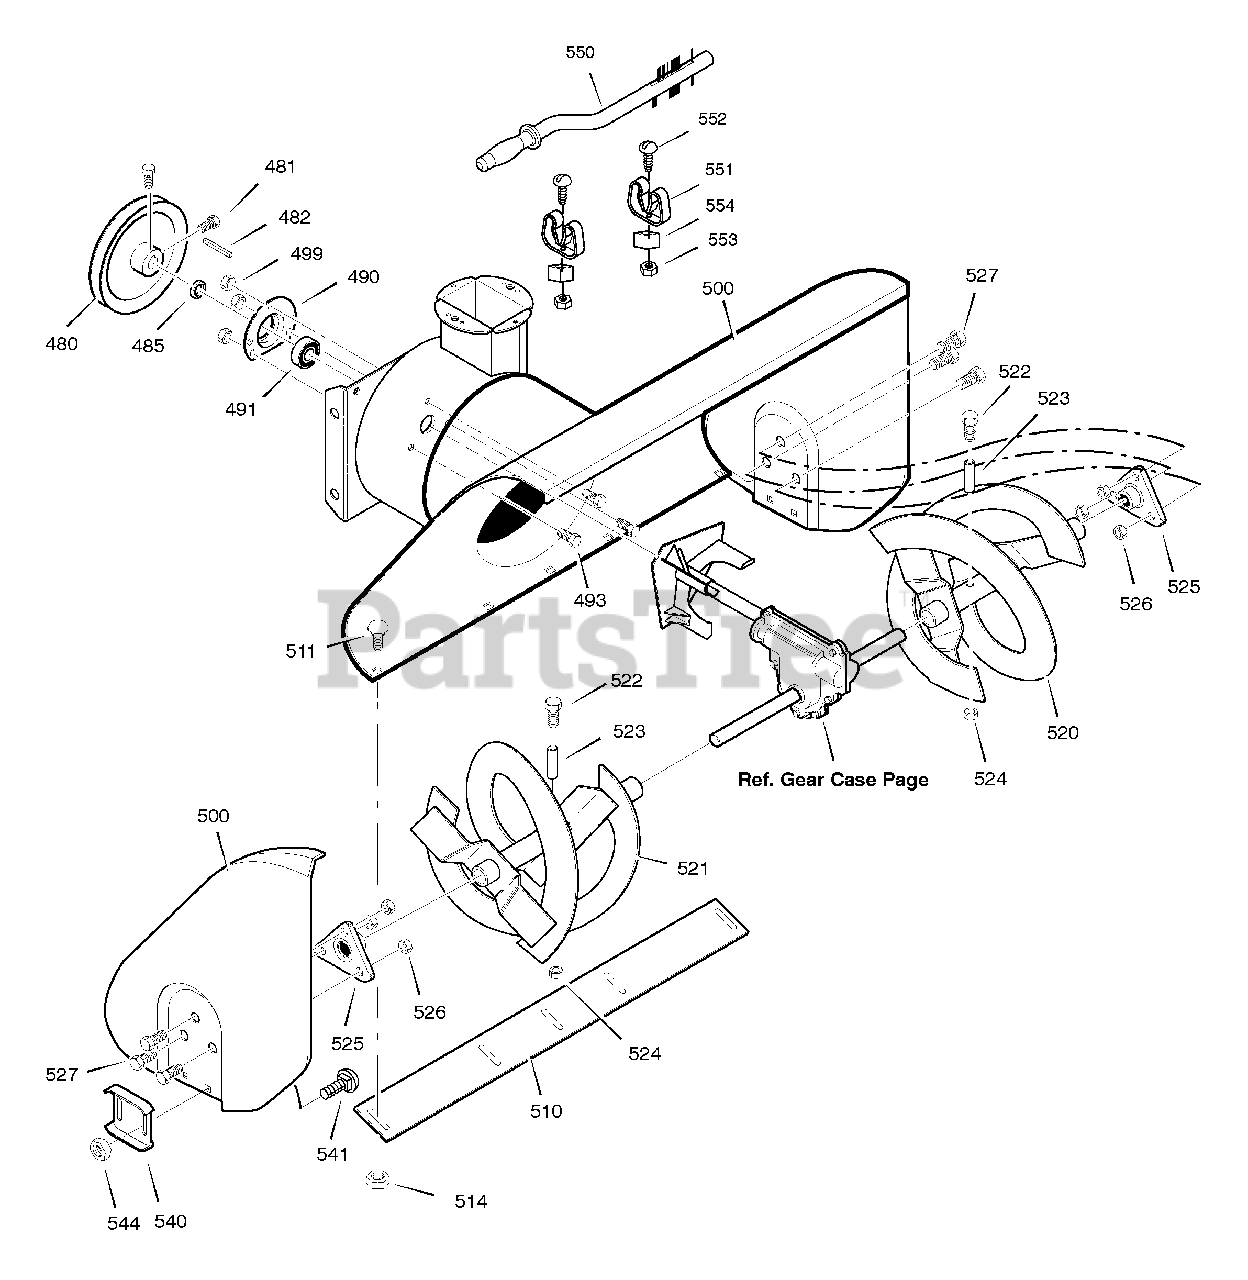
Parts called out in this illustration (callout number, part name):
480	PULLEY, 8.40 V4L .67id
481	SCREW, 5/16-18 x 0.63
482	KEY, SQUARE 3/16 X 3/4
485	SPACER, FRICTION PULLEY
490	RETAINER, BALL BRNG
491	BEARING, BALL
493	BOLT, HEX 5/16-18x0.62
499	NUT, 5/16-18 HEXWDFLLK
500	HOUSING, ASSY
510	BLADE, SCRAPER
511	BOLT, 1/4-20X0.62
514	NUT, 5/16-18x0.62
520	AUGER, ASSY, LH
521	AUGER, ASSY, RH
522	SCREW, 1/4-20X1.75
523	SPACER, SLEEVE
524	NUT, 1/4-20
525	BEARING,FLANGE
526	NUT, 5/16-18
527	SCREW, 5/16-18 x 0.75
540	SKID, HEIGHT ADJUST
541	BOLT, 5/16-18x0.5
544	NUT, 5/16-18
550	BRUSH, CLEANOUT
551	CLIP, RETAINER
552	SCREW
553	NUT
